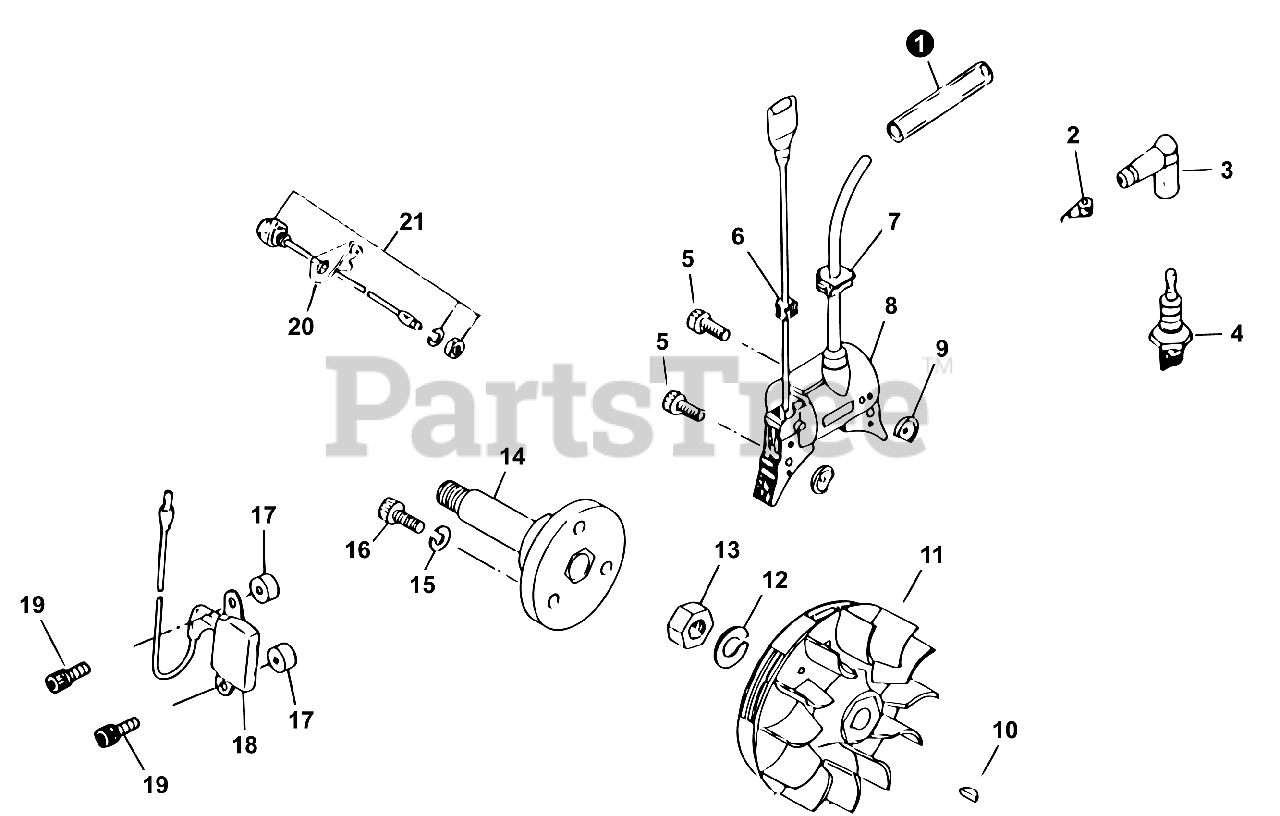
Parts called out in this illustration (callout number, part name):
1	TUBE, INSULATOR
2	TERMINAL, SPARK PLUG
3	CAP, SPARK PLUG
4	SPARK PLUG - CJ8
5	BOLT M4×26
6	GROMMET, LEAD
7	GROMMET
8	COIL, IGNITION
9	COLLAR 4
10	KEY, WOODRUFF 3×10
11	FLYWHEEL
12	WASHER, SPRING 10
13	NUT 10×1.25
14	SHAFT, PUMP
15	WASHER, SPRING 6 MM
16	BOLT 6×20
17	INSULATOR 4.2×11×6
18	ELECTRONIC UNIT
19	BOLT M4×16
20	BRACKET
21	SWITCH, ON-OFF
